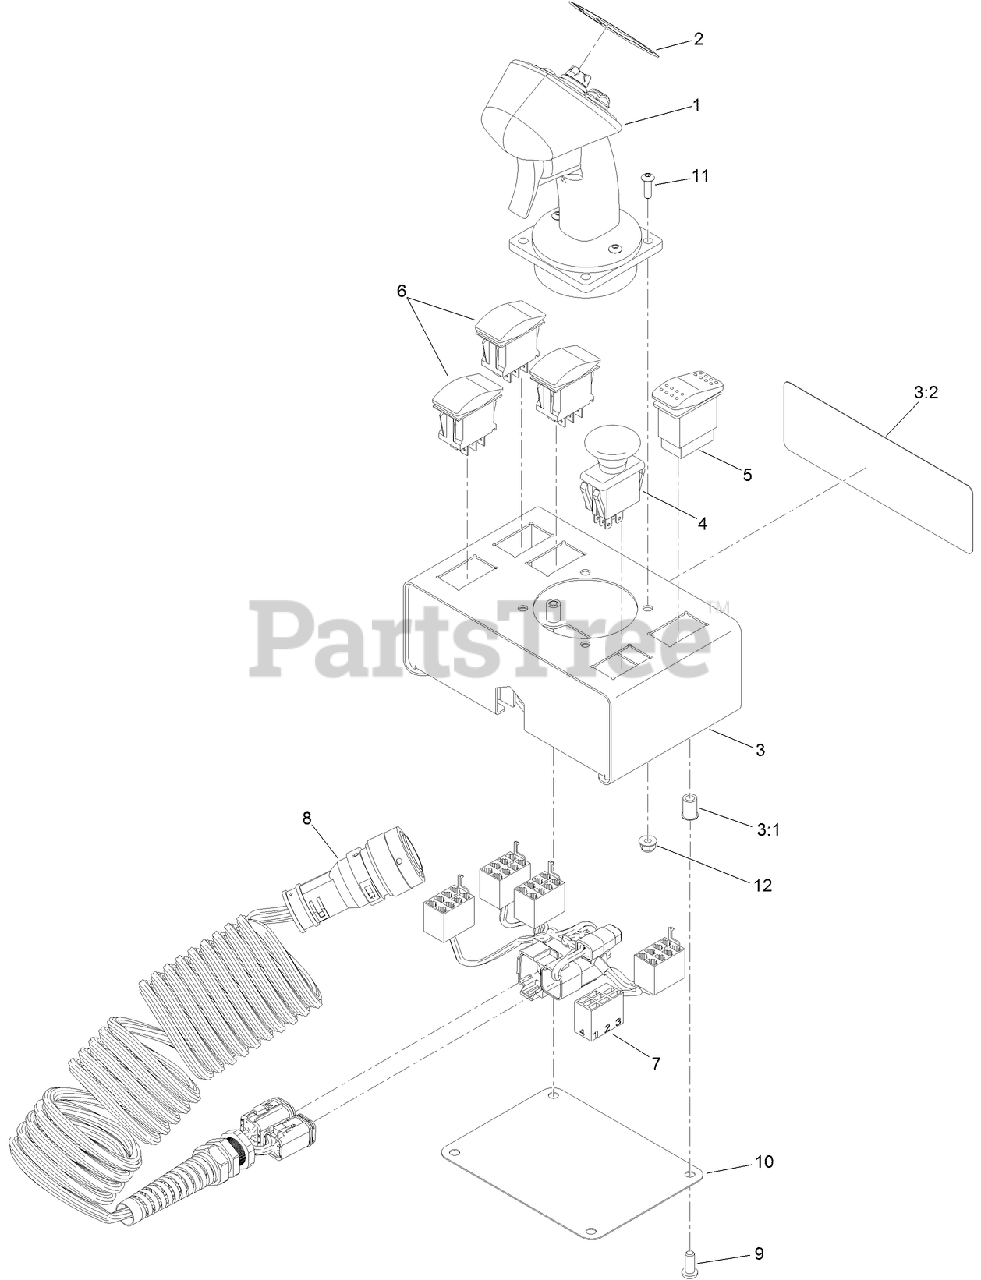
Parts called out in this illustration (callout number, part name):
1	JOYSTICK-GRIP, FIXED
2	DECAL-PENDANT, OVAL
3	TRAVEL PENDANT ASM
3:1	NUT-CLINCH
3:2	DECAL-PENDANT, CONTROLS
4	SWITCH, E-STOP
5	SWITCH-INTERMITTENT
6	SWITCH
7	HARNESS-WIRE
8	HARNESS-WIRE
9	SCREW-HSBH
10	COVER-PENDANT
11	SCREW-HSBH
12	NUT-HF
